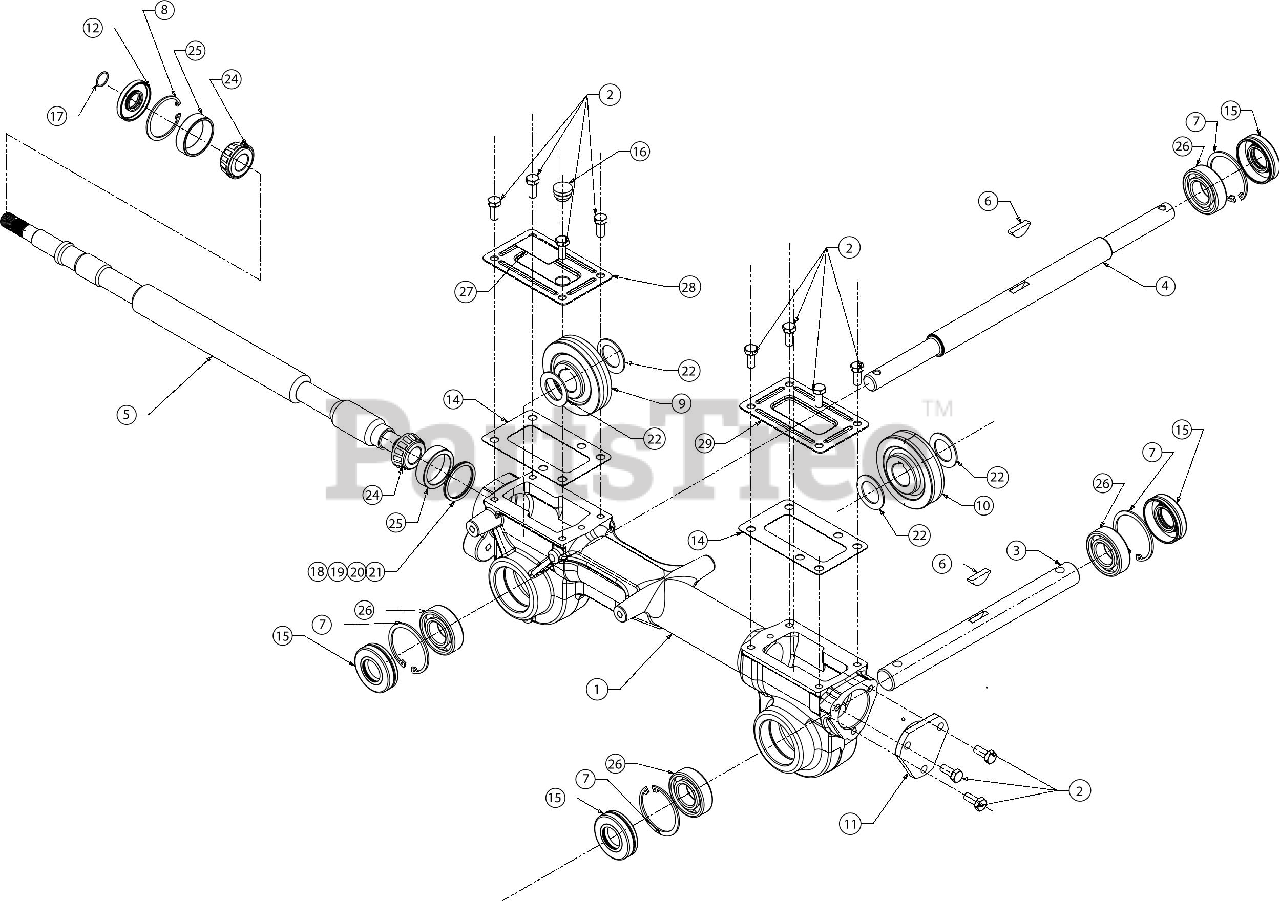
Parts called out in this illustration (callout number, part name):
1	HOUSING ASSEMBLY
2	SCREW 5/16-18 x .75 GR5
3	TILLER SHAFT
4	WHEEL SHAFT
5	WORM DRIVE SHAFT
6	KEY-HI PRO .25 X 1
7	RETAINING RING
8	RETAINING RING
9	WORM GEAR (RH) 61T
10	WORM GEAR (LH) 30T
11	BEARING COVER
12	OIL SEAL .750 SHF X 1.783
14	GEAR HOUSING GASKET
15	OIL SEAL 1.00 SHF X 2.00 BORE
16	RUBBER OIL PLUG
17	WIRE RING
18	FLAT WASHER 1.500X1.750X.062
19	FLAT WASHER 1.500X1.750X.005
20	FLAT WASHER 1.500X1.750X.030
21	FLAT WASHER 1.500X1.750X0.010
22	WASHER 1.010X1.560X.060
24	BEARING CONE
25	BEARING CUP
26	BALL BEARING
28	TRANSMISSION COVER
29	TRANSMISSION COVER
